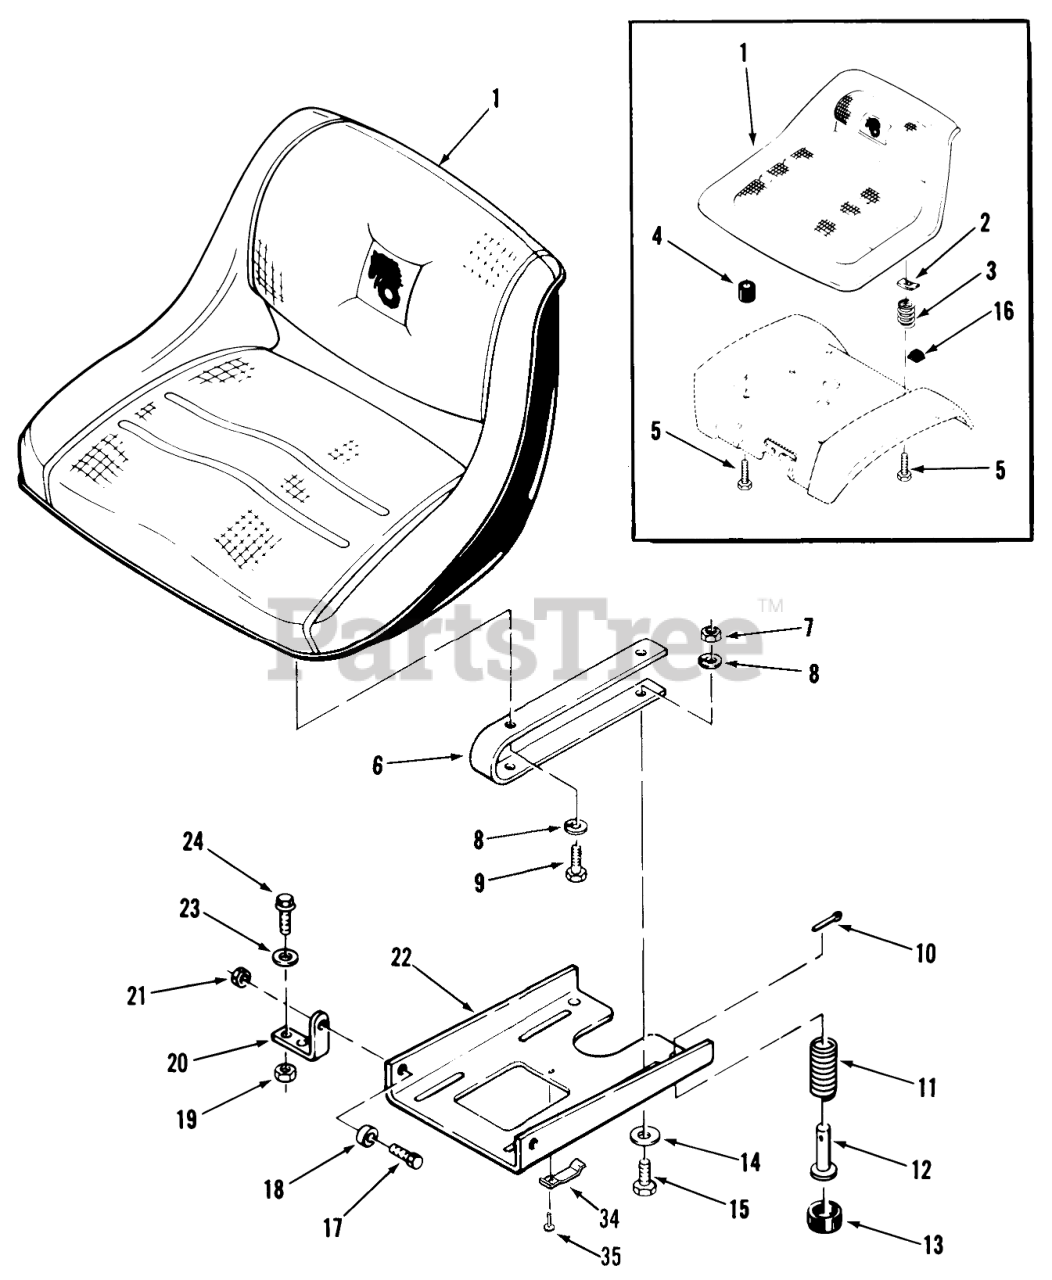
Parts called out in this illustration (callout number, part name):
1	ASSY-SEAT
2	NUT-PUSH
3	SPRING
4	GROMMET-RUBBER
5	SPECIAL BOLT
6	Seat Spring
7	Nut
8	Lockwasher
9	Bolt
10	Cotter Pin
11	SPRING
14	WASHER 5/16 SAE
15	HHCS
16	BUMPER
17	HHCS
18	BUSHING
19	Nut
20	BRACKET-PIVOT
21	Nut
22	PLATE SEAT PIVOT B
23	WASHER 5/16 SAE
24	HHCS
34	SPRING SWITCH
35	RIVET
